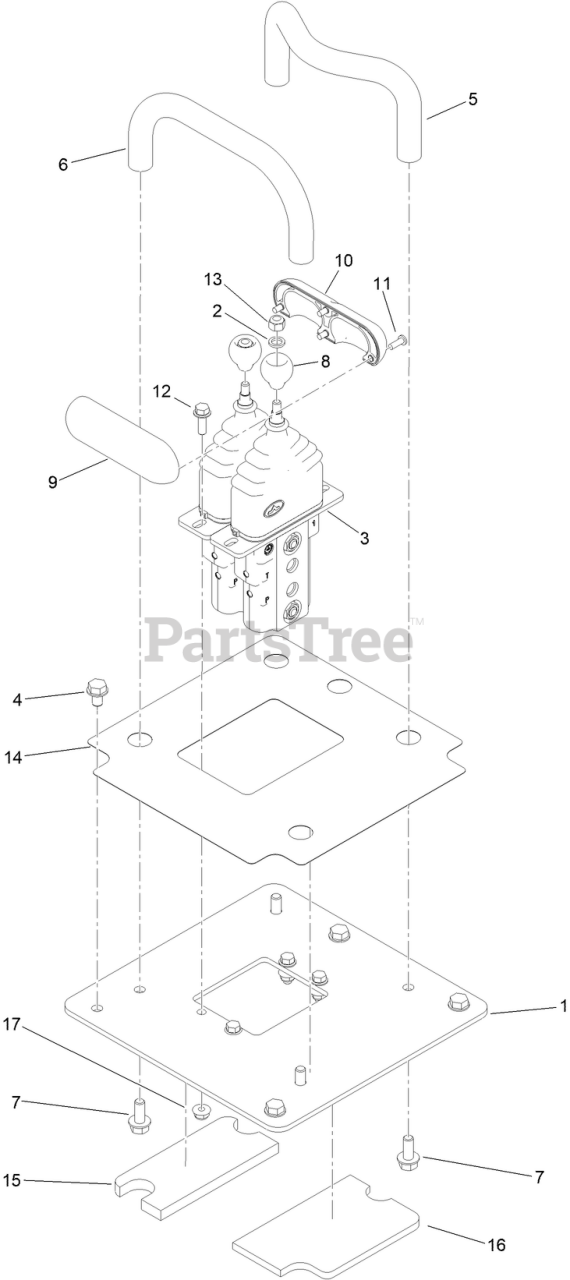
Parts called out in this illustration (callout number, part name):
1	PANEL-COVER
2	SPACER-BEARING
3	VALVE-CONTROL (TRACTION)
4	SCREW-HWH
5	BAR-REFERENCE
6	BAR-REFERENCE
7	SCREW-HHF
8	BALL-TRACTION
9	HANDLE-CONTROL
10	HANDLE-TRACTION
11	SCREW
12	SCREW-HHF
13	NUT-LOCK, NI
14	DECAL-TRACTION
15	FOAM-SHIELD, HEAT
16	FOAM-SHIELD, HEAT
17	NUT-HF
